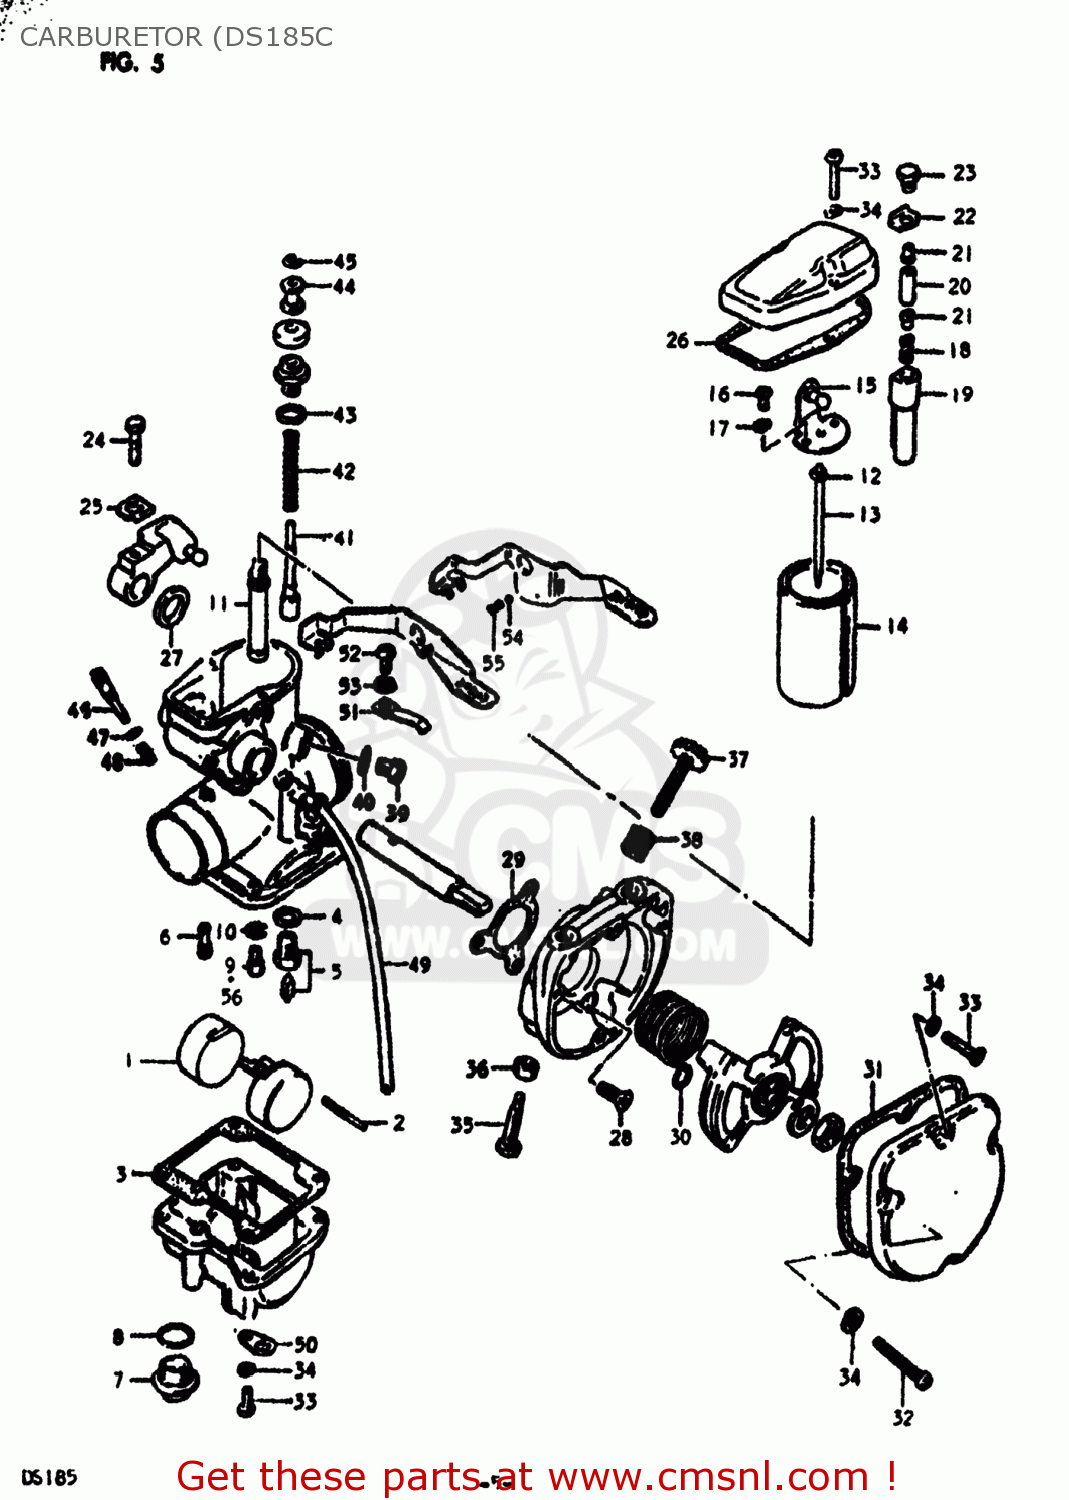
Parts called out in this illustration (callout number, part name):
0	CARBURETOR ASSEMBLY
1	FLOAT
2	PIN,FLOAT
3	GASKET,FLOAT CHAMBER (NAS)
4	GASKET,VALVE SEAT (NAS)
5	VALVE ASSEMBLY,NEEDLE
6	JET
7	PLUG,DRAIN
8	O RING
9	JET
10	WASHER
11	JET,NEEDLE
12	CLIP
14	VALVE,THROTTLE
15	BRACKET,CARBURETOR
16	SCREW
17	LOCK WASHER
18	SPRING
19	LEVER ASSEMBLY
20	SPRING
21	PIN,CARBURETOR
22	PLATE,CARBURETOR
23	SCREW
24	BOLT
25	RING
26	GASKET,MIXING CHAMBER (NAS)
27	RING
28	SCREW(5X14)
29	GASKET,CARBURETOR CASE
30	SPRING
31	GASKET,CARBURETOR COVER
32	SCREW 4X25
33	SCREW
34	LOCK WASHER
35	SCREW
36	NUT 6MM
37	SCREW,THROTTLE STOP
38	SPRING,THROTTLE SCREW
39	BOLT
40	GASKET,THRO VALVE INSPECTION (NAS)
41	VALVE,STARTER
42	SPRING
43	O-RING
44	RING
45	CLIP,CARBURETOR STARTER
46	SCREW,PILOT AIR ADJUSTING
47	O RING
48	SPRING
49	HOSE
50	PLATE
51	SPRING
52	SCREW
53	LOCK WASHER
54	BALL,STARTER SHAFT
55	SPRING
56	JET
